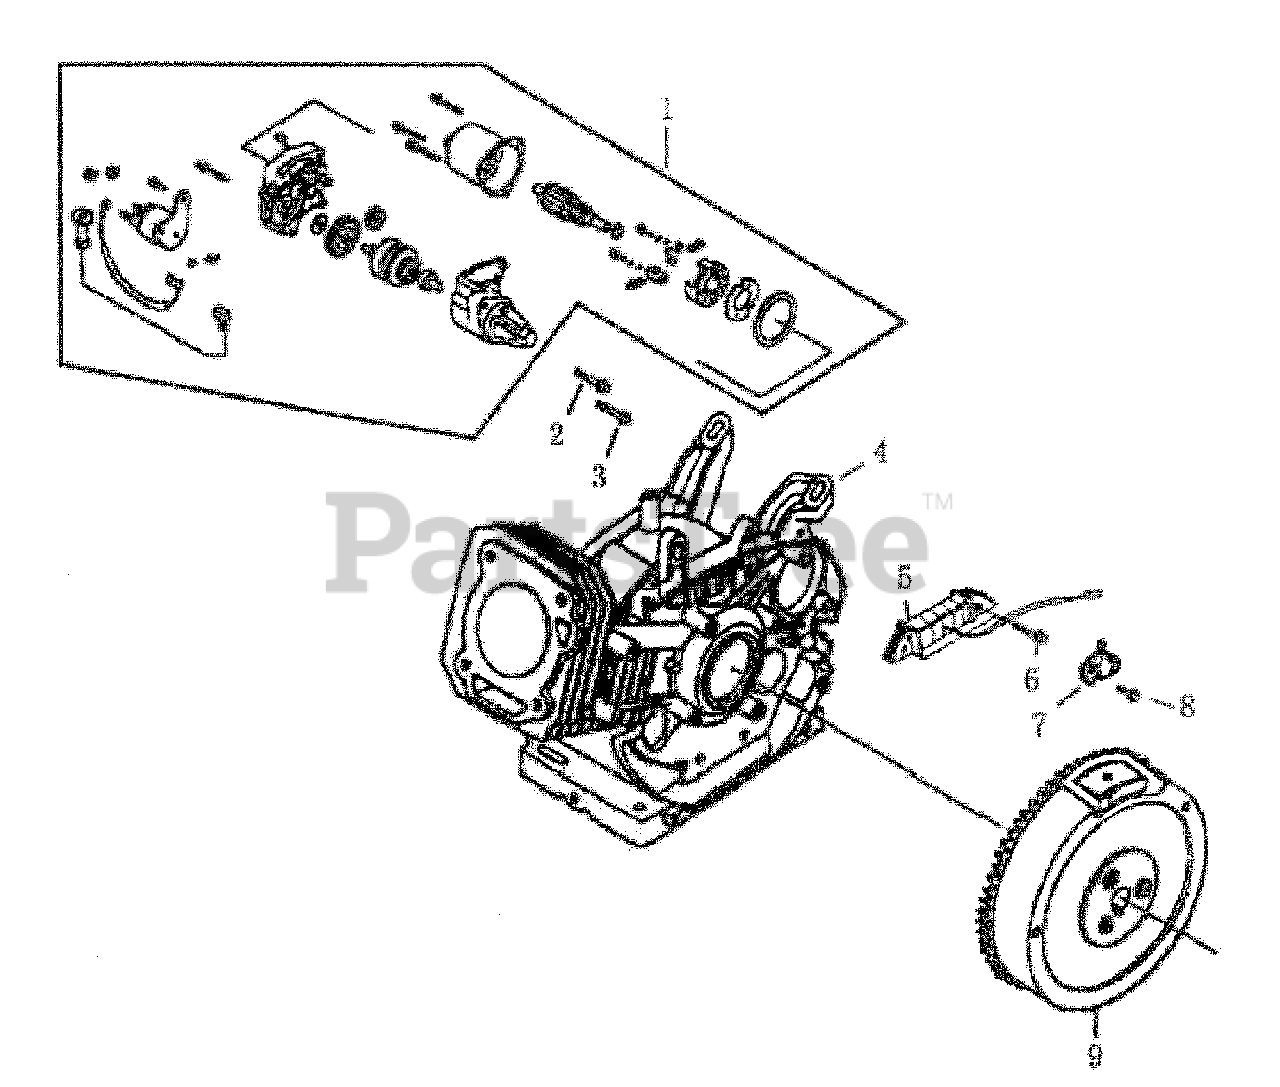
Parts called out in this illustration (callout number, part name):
1	MOTOR ASSY.' STARTER
2	BOLT' M6X28
3	BOLT' M6X32
4	CRANKCASE
5	COIL' CHARGE
6	BOLT' M6X35
7	CORD' CLAMP
8	BOLT' M6X12
